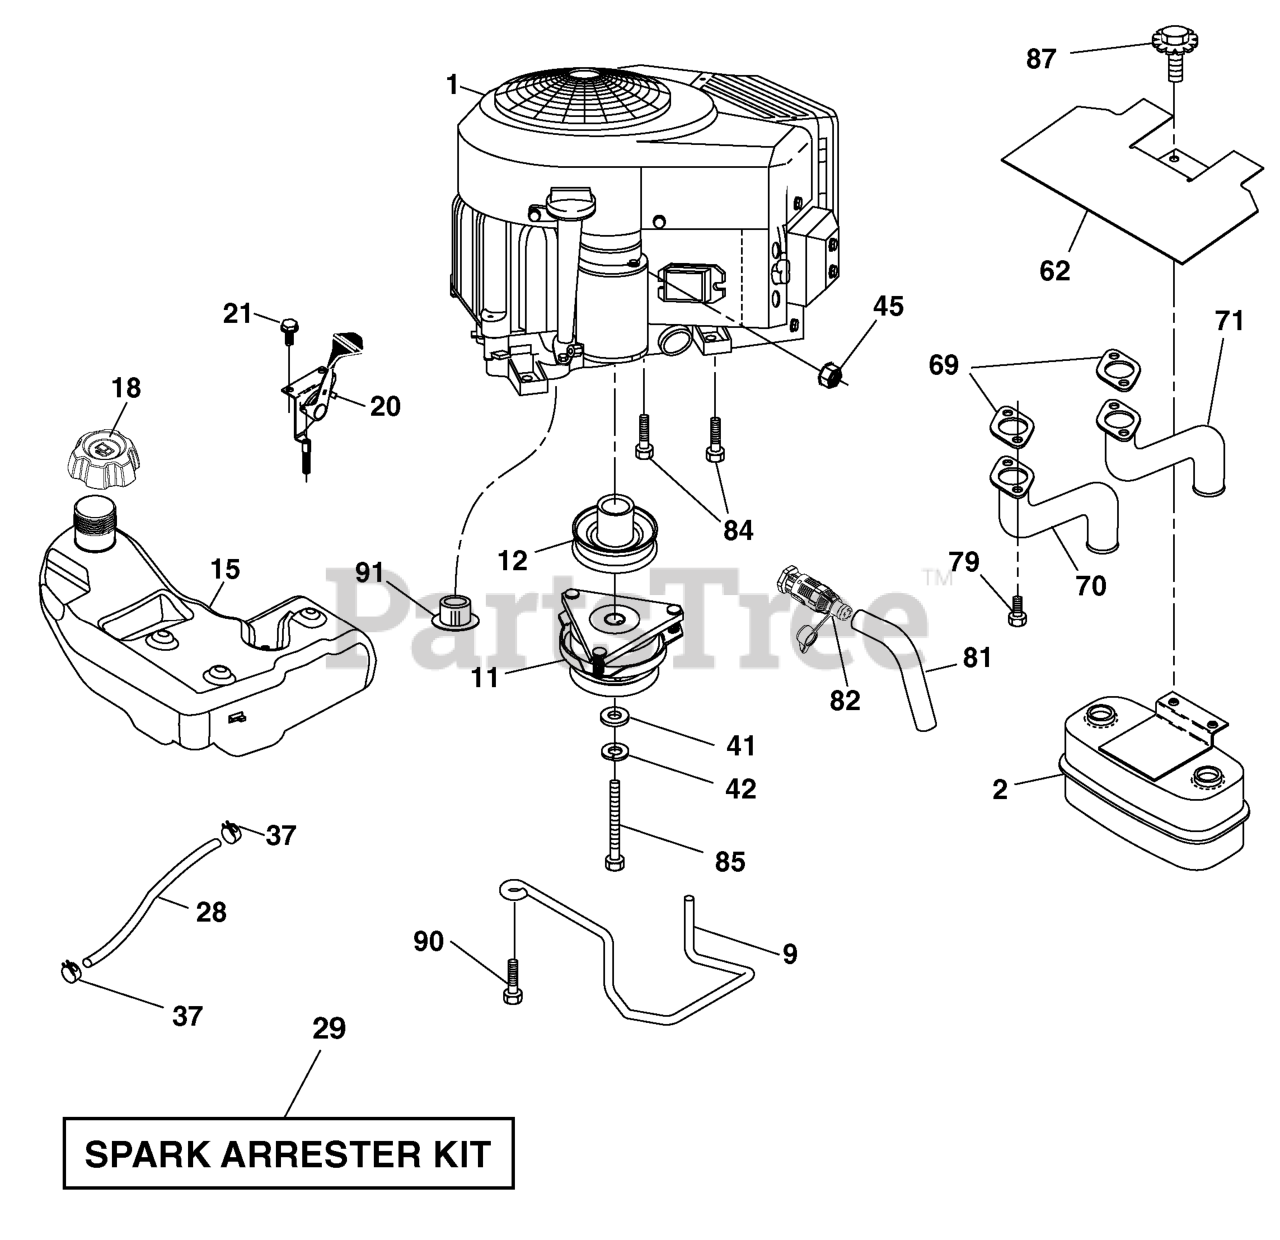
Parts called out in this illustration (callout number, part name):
1	ENGINE, 26 Gross HP Briggs & Stratton
2	Muffler
9	Keeper Asm. Belt Engine
11	Clutch Electric
12	Pulley Engine
15	Tank Fuel 4.0
18	Cap Asm
20	Control
21	Screw 10 x .750 BOS Thread
28	Fuel Line
29	Spark Arrester Kit
37	Clamp Hose
41	Washer 1-1/2 OD x 15/32 ID x .250
42	Washer Lock 7/16
45	Nut Keps 1/4-20 unc
62	Shield Heat Muffler
69	Gasket
70	Tube Exhaust LH
71	Tube Exhaust RH
79	Screw Socket Head 5/16-18 x 1
81	Tube Drain Oil Easy
82	Valve Oil Drain
84	Screw 3/8-16 x 1-1/4
85	Bolt Hex 7/16-20 x 3.75 Gr. 5
87	Bolt 5/16-18 unc x 1 w/Sems
90	Screw 3/8-16 x 1
91	Bushing
